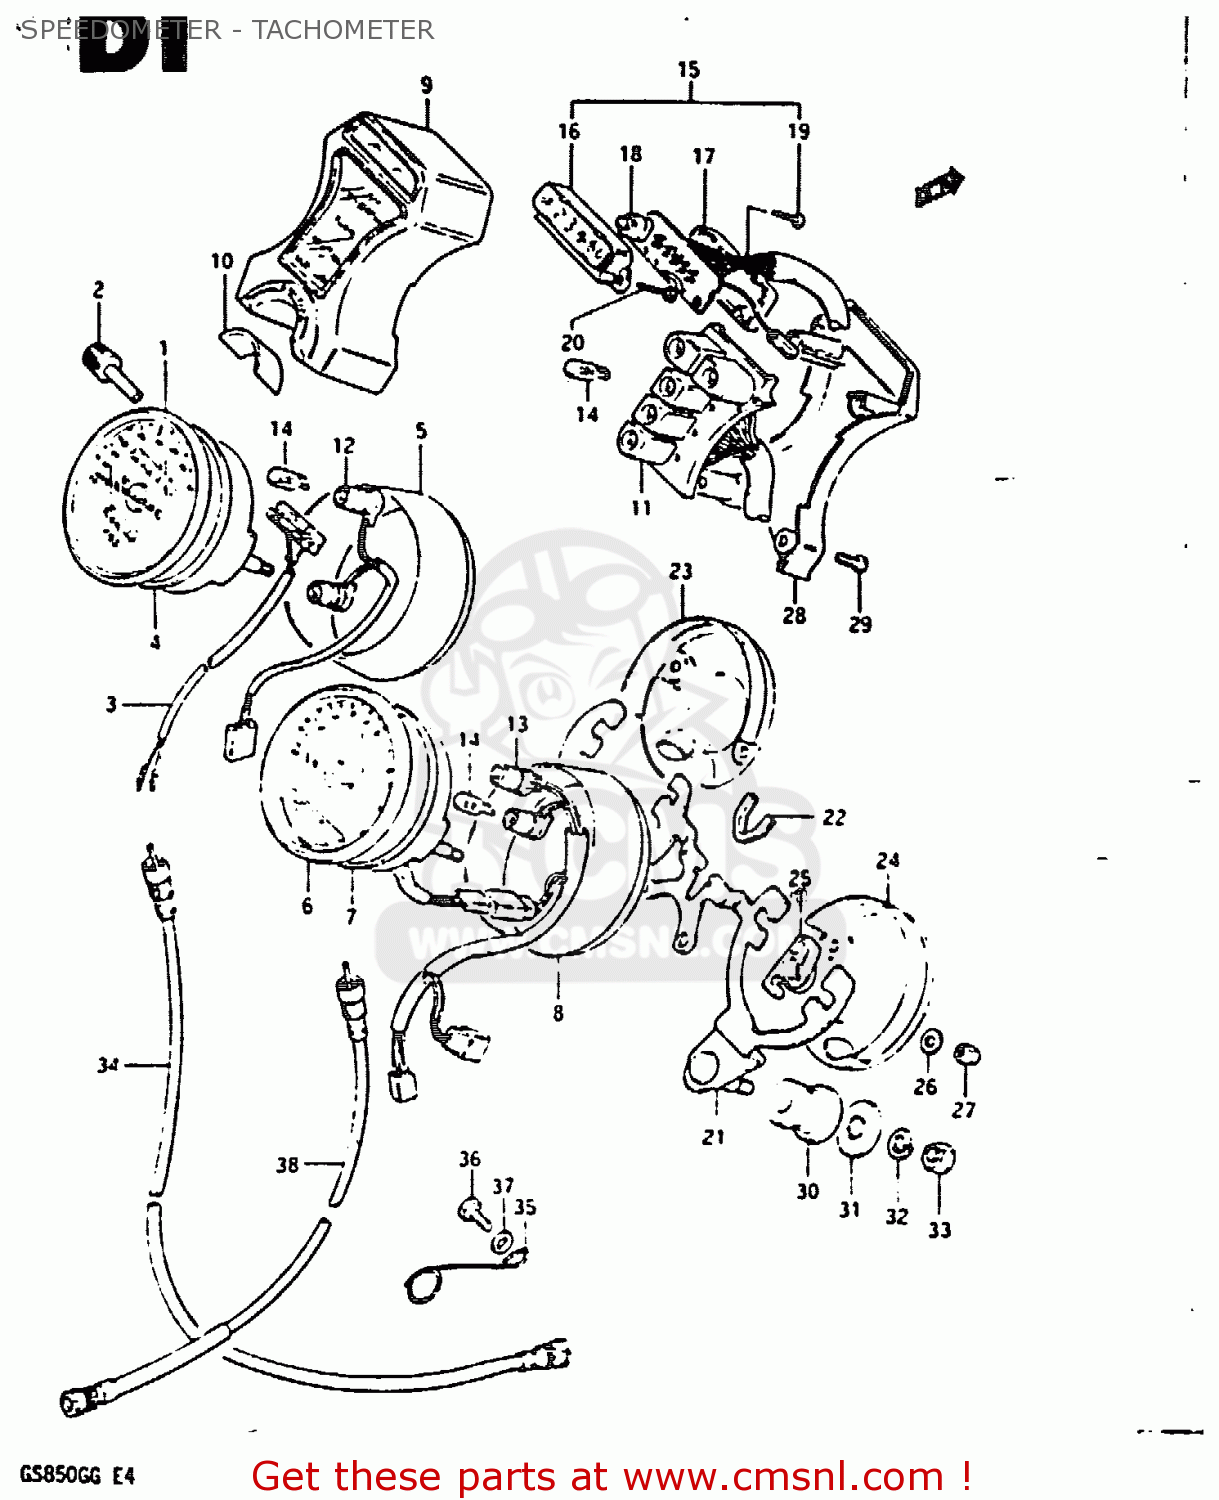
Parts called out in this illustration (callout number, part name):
1	SPEEDOMETER (KILO)
2	KNOB,TRIP
3	WIRE,LEAD SWITCH
4	CUSHION,METER
5	COVER,SPEEDOMETER
6	METER,TACHOMETER
7	CUSHION,METER
8	COVER,TACHOMETER
9	CASE,PILOT BOX
10	SEAL,IGNITION SWITCH
11	SOCKET,PILOT BOX
12	SOCKET,SPEEDOMETER
13	SOCKET,TACHOMETER
14	BULB(12V3.4W,T10)
15	INDICATOR ASSEMBLY,GEAR POSITION
16	CASE,GEAR INDICATOR
17	COVER,LWR
18	BULB(14V1.12W,BQ041-32503B)
19	SCREW,GEAR INDICATOR
20	SCREW
21	BRACKET,COMBINATION METER
22	BRACKET,COVER
23	COVER,METER,UNDER
24	COVER,TACHOMETER,UNDER
25	CUSHION
26	WASHER
27	NUT
28	COVER,PILOT BOX LWR
29	SCREW,PILOT BULB CASE
30	CUSHION,METER BRACKET
31	WASHER (8.5X20X1.6)
32	WASHER,LOCK,8.
33	NUT
34	CABLE ASSEMBLY,SPEEDOMETER
35	CLAMP,SPEEDOMETER CABLE
36	BOLT
37	WASHER
38	CABLE ASSEMBLY,TACHOMETER
